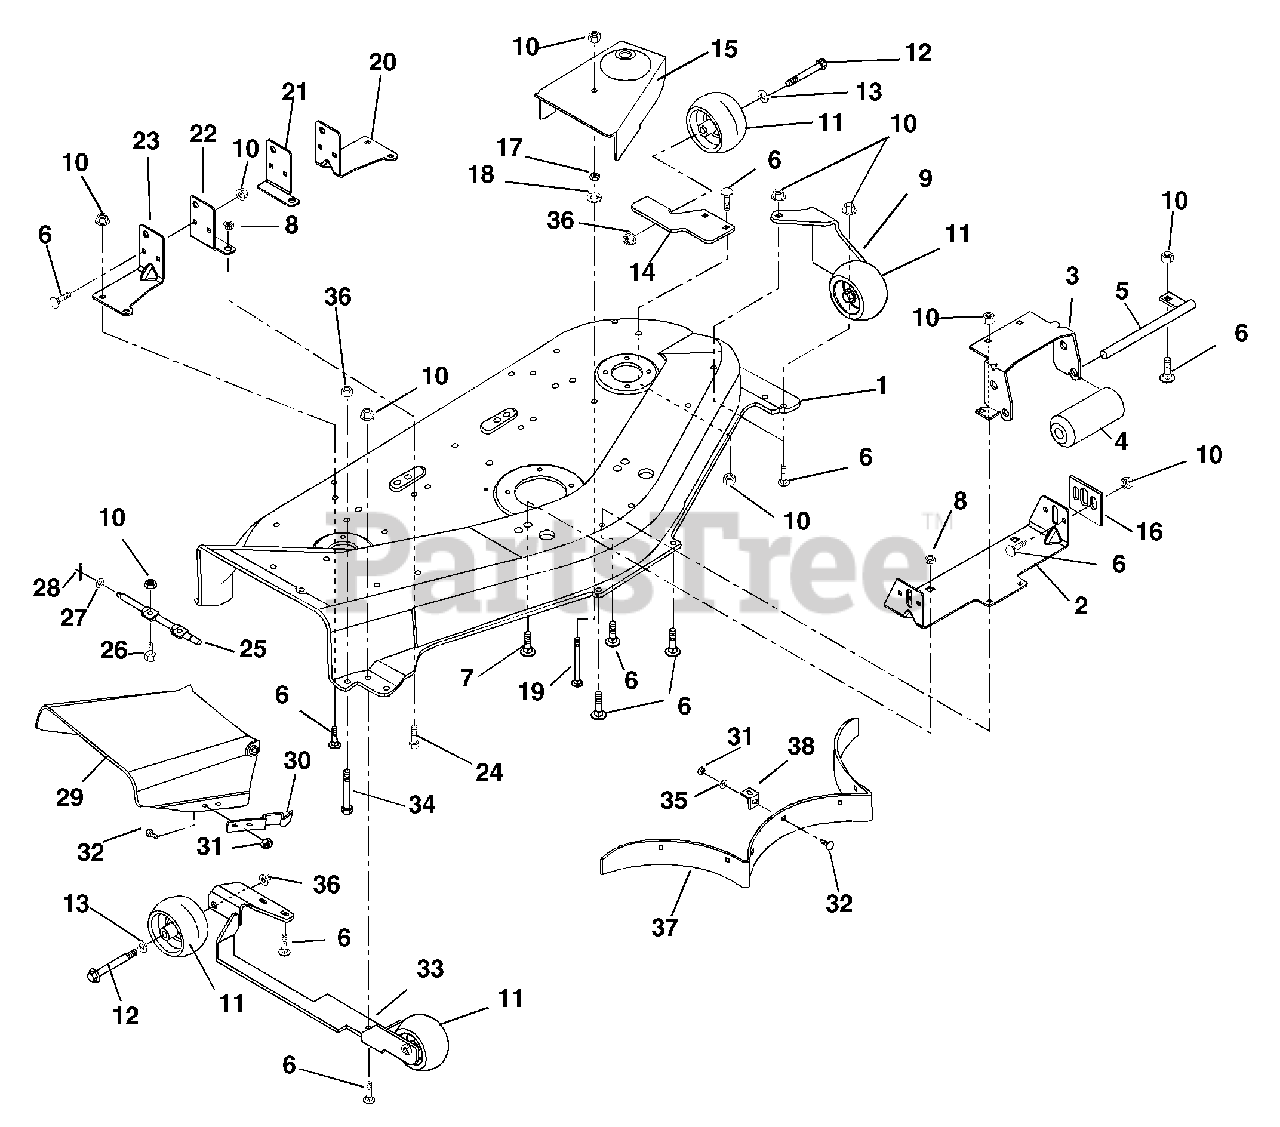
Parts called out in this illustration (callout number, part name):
1	MOWER PAN W/DECALS 48"- ORANGE
2	FRONT HANGER
3	BRACKET, ROLLER
5	ROLLER SHAFT
6	@BLT-RDHDSQNK .31-18X.75 G5YZ
7	@BLT-RDHDSQNK .50-13X1.00 G5YZ
8	@NUT-LK-TOP-FLG .50-13 YWZC
9	BRACKET, LEFT FRONT
10	@NUT-LK-TOP-FLG .31-18 YWZC
11	WHEEL 5 X 3
12	BLT-SHLDR .38-16X2.50 HWH G5
13	WSHR-FL-NYL .518X1.000X.080
14	BRACKET, LEFT REAR
15	COVER, RH BELT
15	COVER, LH BELT
16	MOWER ADJUSTMENT TAB
17	@NUT-HEX .31-18 YWZC
18	WSHR-LK .312X.097 HVY YWZC
19	BLT-RDHDSQNK .312-18X3.25 YWZC
20	LH REAR HANGER
21	LEFT HAND REAR HANGER SUPPORT
22	RH REAR HANGER SUPPORT
23	RH REAR HANGER
24	@BLT-HEX .50-13X1.00 GR5 YWZC
25	HINGE PIN
26	@BLT-HEX .31-18X.75 GR5 YWZC
27	@WSHR-FL-STL.406X.812X.065 YWZ
28	@PIN-CTR .09X.75 EXTPRSQCT YWZ
29	CHUTE EXTENSION
30	SPRING, FLAT
31	@NUT-LK-CTR .25-20 YWZC
32	@BLT-RDHDSQNK .25-20X.50 G5YZ
33	MOUNT ROLLER
34	@BLT-RDHDSQNK .38-16X2.50 G5YZ
35	@WSHR-FL-STL.281X.62X.065 YWZC
36	@NUT-LK-TOP-FLG .38-16 YWZC
37	BAFFLE
38	BAFFLE TAB
